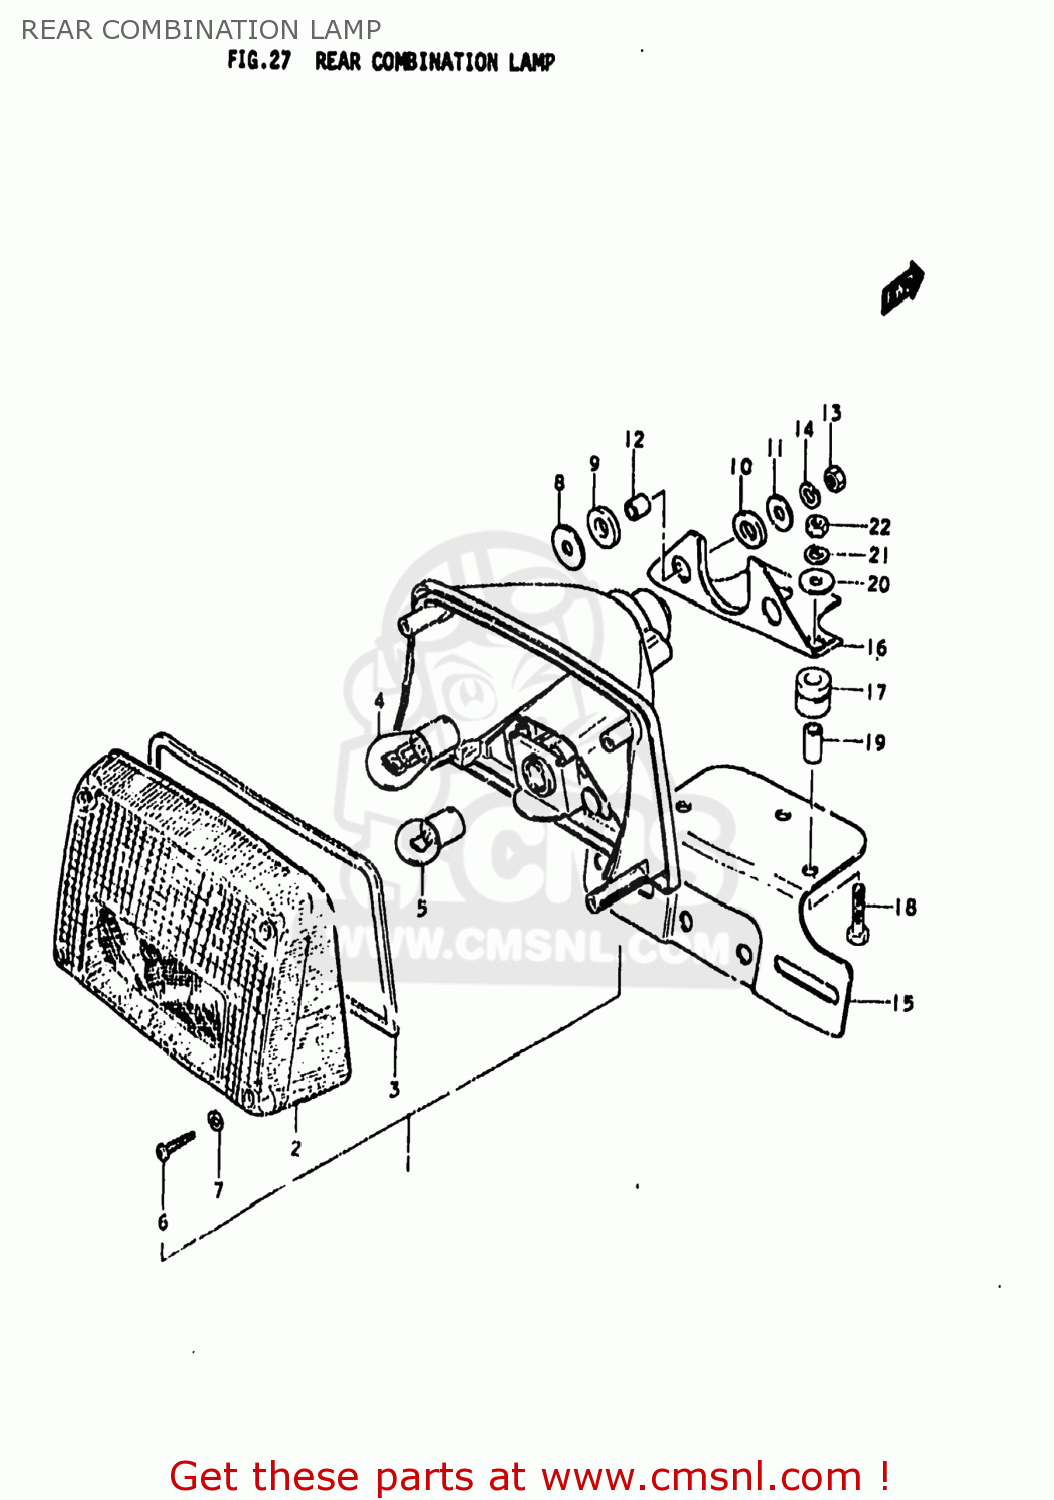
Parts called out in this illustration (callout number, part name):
1	LAMP ASSEMBLY,REAR COMBINATION
2	LENS
3	GASKET (NAS)
4	BULB(12V23W)
5	BULB
6	SCREW
7	GASKET (NAS)
8	WASHER
9	CUSHION
10	CUSHION
11	WASHER (6.5X24X1.6)
12	SPACER(6.1X9X7.5)
13	NUT
14	LOCK WASHER
15	BRACKET,LICENSE PLATE
16	BRACKET,LICENSE PLATE
17	CUSHION, BRACKET
18	BOLT
19	SPACER (6.1X8X15.5)
20	WASHER
21	LOCK WASHER
22	NUT
